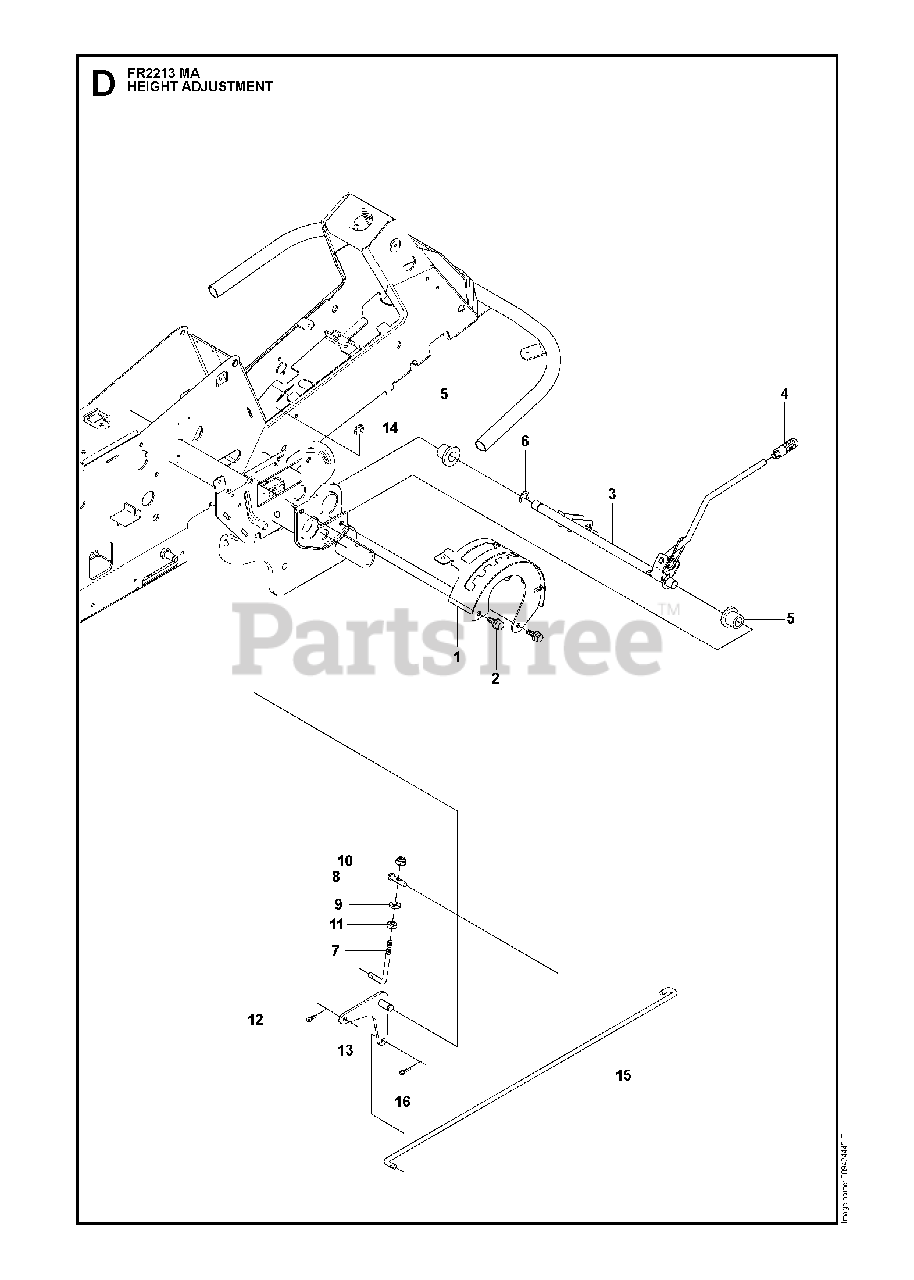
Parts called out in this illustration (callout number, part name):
4	GEAR STICK KNOB
5	BUSHING
9	WASHER
10	LOCKNUT M8
11	NUT
12	SPLIT PIN
14	RETAINING RING
16	SPLIT PIN
